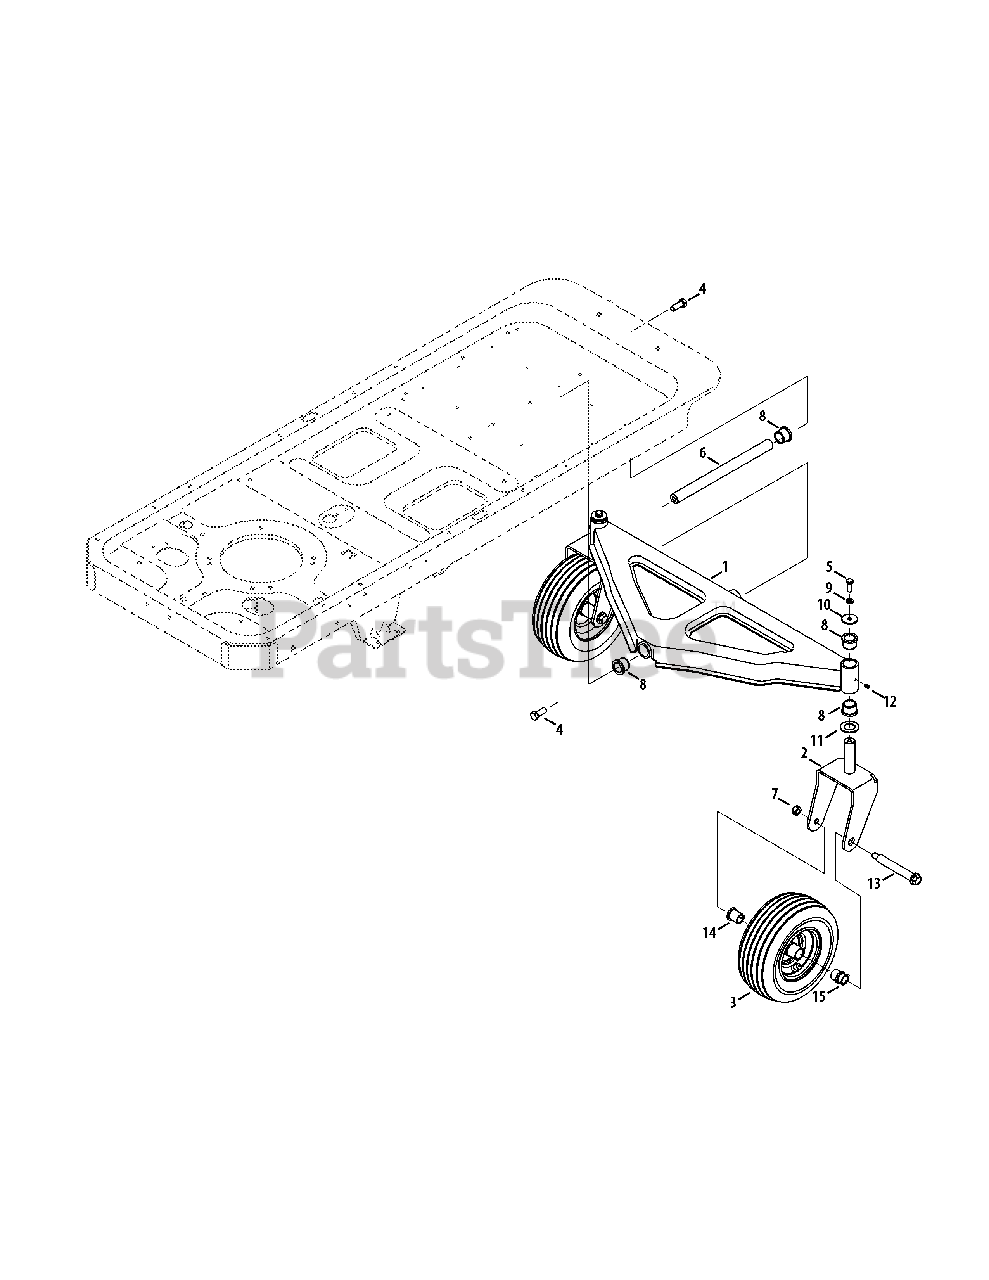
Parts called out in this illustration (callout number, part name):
1	Front Pivot Axle
2	Castor Wheel Bracket
3	Wheel Assembly, 11.0 x 4.0 x 5.0
4	Hex Lock Screw, 1/2-13 x 1.25
5	Hex Cap Screw, 3/8-16 x 1.0
6	Axle Shaft
7	Hex Lock Nut, 1/2-13
8	Flange Bearing, 1.0 x 1.246
9	Lock Washer, 3/8
10	Flat Washer, .39 x 1.5 x .134
11	Flat Washer, 1.0 x 1.75 x .107
12	Lube Fitting, 3/16
13	Shoulder Screw, 7/16-14 x .75 x 4.75
14	Flange Bearing, .76 x 1.0 x 1.2
15	Flange Bearing, .76 ID w/Lube Ftg.
